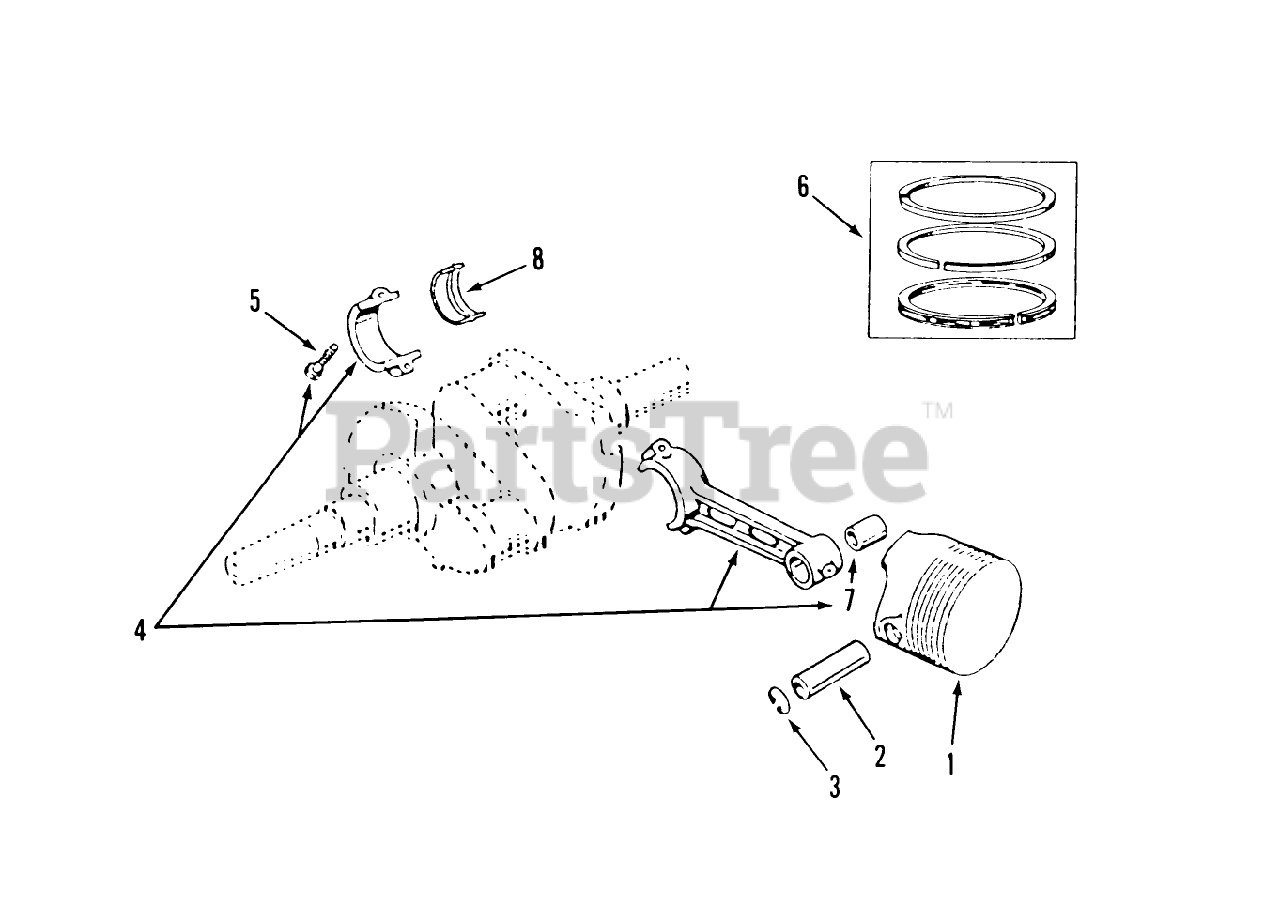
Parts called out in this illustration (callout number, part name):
1	Piston Pin (Incl. Pin Retaining Ring)
2	PIN-PISTON
4	ROD-CONNECTING
5	BOLT-PLACE
6	Set-Piston Ring
7	BUSHING-PISTON PIN
8	Bearing-Connecting Rod, Half
